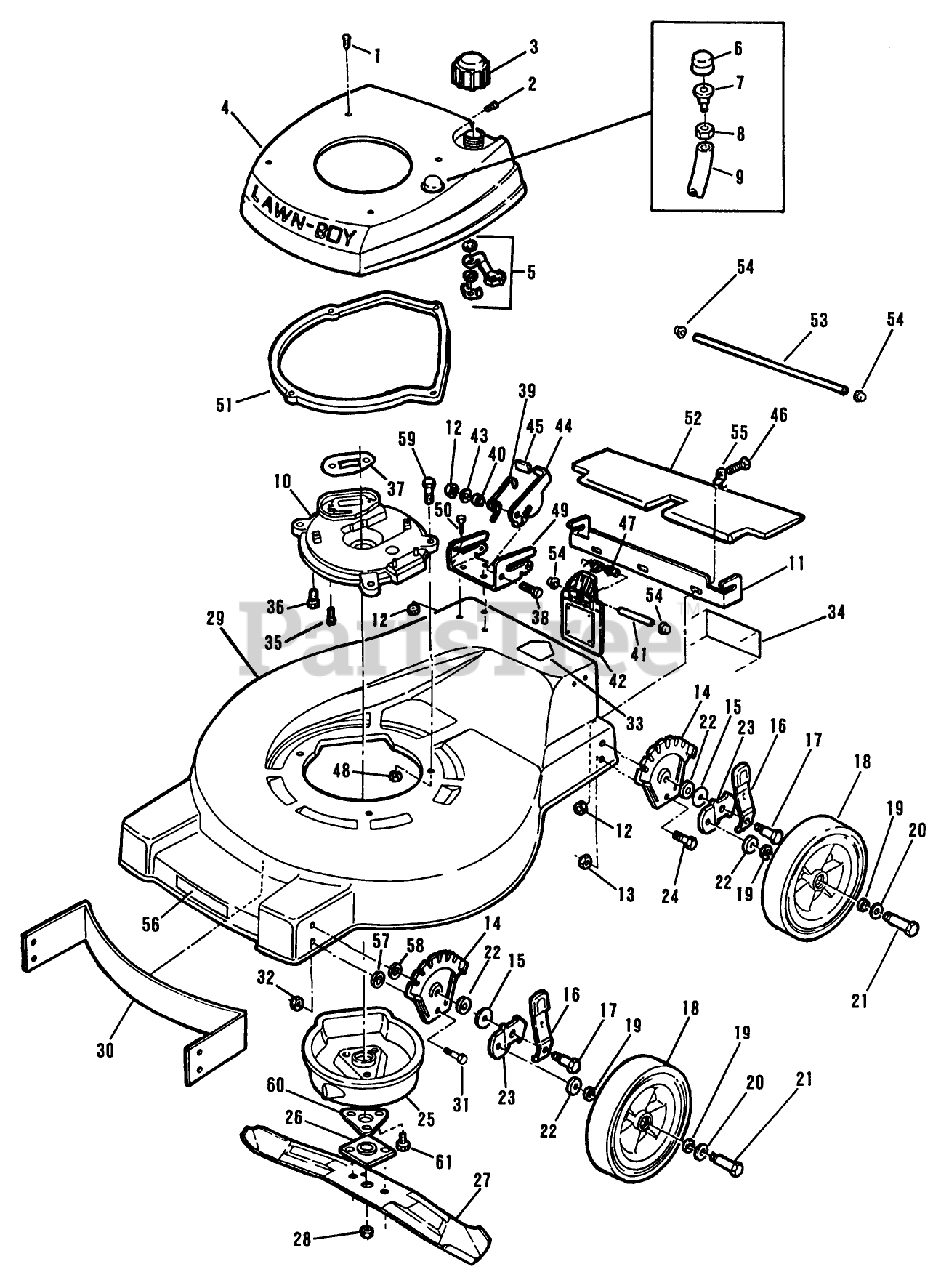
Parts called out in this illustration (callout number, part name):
1	SCREW LAWRENCE
2	SCREW S
3	FUEL CAP & INSERT
4	SHROUD,TANK&VAVLE
6	P-BULB LAV-RUB
8	LOCKNUT S
9	TUBING-PRIMER POLY
10	PLATE,MUFFLER F
12	LOCKNUT E
13	LOCKNUT
15	WASHER
16	KNOB&SPRING FORMCO
17	BOLT
19	WASHER
20	SPACER
21	BOLT WHEEL
22	WASHER WROUGHT
26	PLATE AND COLLAR ASM
28	NUT-BLADE
32	LOCKNUT
35	SCREW V
37	GASKET-EXHAUST F
39	SPRING
41	ROD ROCK/HDWE
45	KNOB (S&R)
47	SPRING ASOC
48	NUT-LOCK F
52	T/SHIELD SM&P
57	WASHER
58	WASHER
59	SCREW-HH
60	SUPPORT F
61	SCREW
